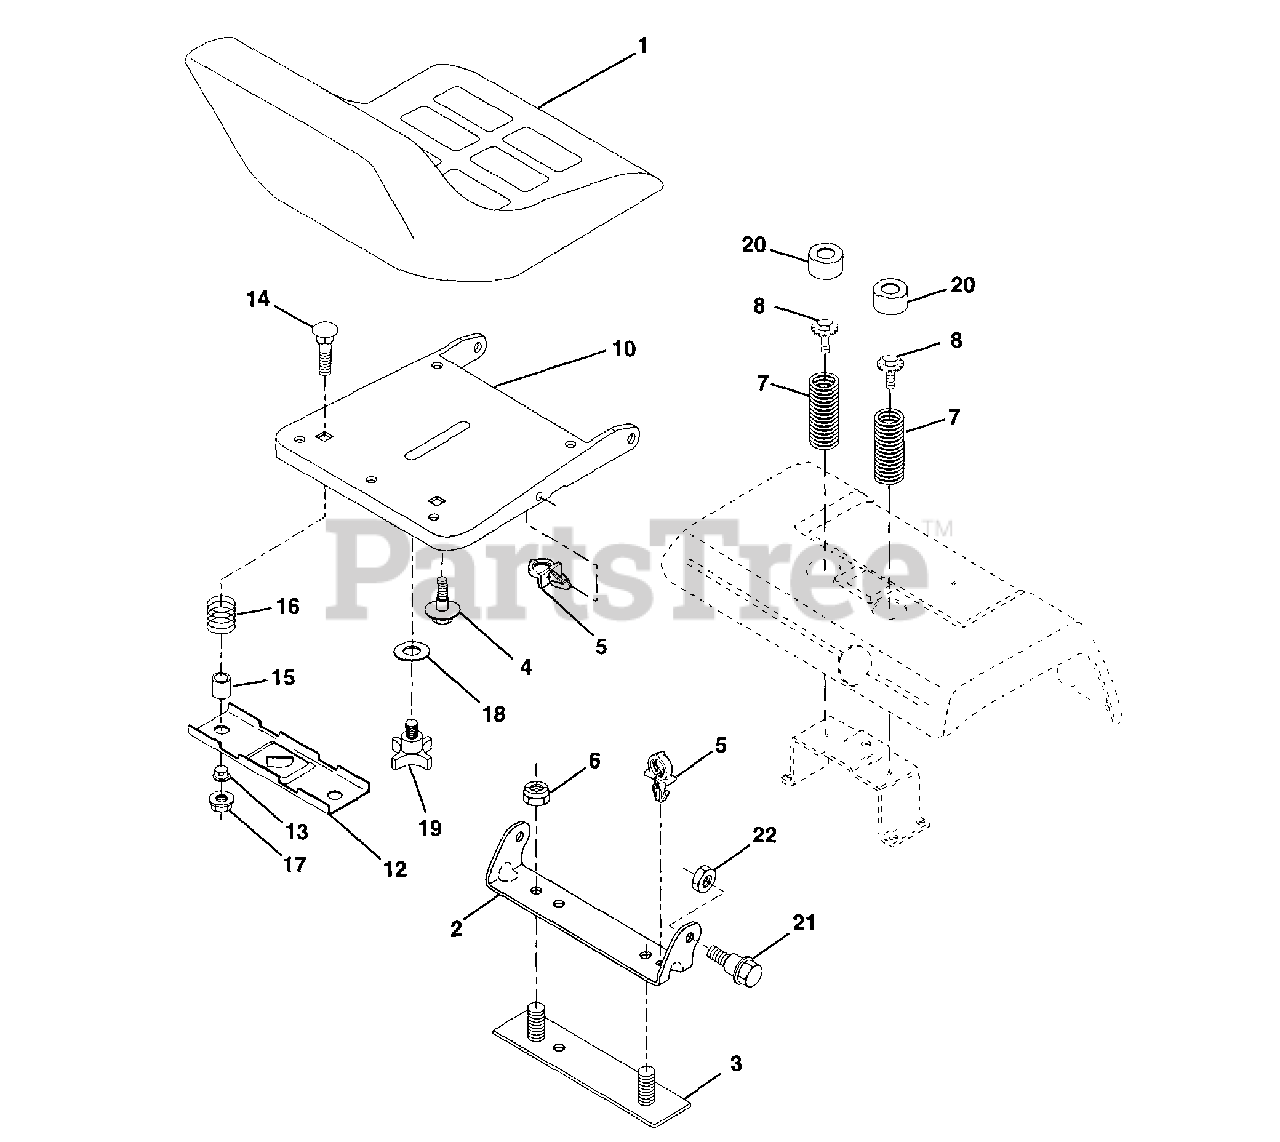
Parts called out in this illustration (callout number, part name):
1	Seat
2	Bracket, Pivot Seat
3	Strap, Fender
4	Bolt, Shoulder 5/16-18 X .62
5	Clip, Push In Hinged
6	Nut, Lock Hex W/Ins. 3/8-16 Unc
7	Spring, Seat Cprsn
8	Screw, Thdrol 5/16-18 X 1/2
9	Washer 13/32 X 1 X 14 Ga.
10	Pan, Seat
12	Bracket, Mounting Switch
13	Bushing, Snap
14	Bolt, Carriage 1/4-20 X 1-3/8
15	Spacer, Split
16	Spring, Cprsn
17	Nut, Lock 1/4 Lge Flg Gr. 5
18	Washer 17/32 X 1-3/16 X 12 Ga.
19	Knob, Seat 1/2-13 Unc
20	Cap, Spring Seat
21	Bolt, Shoulder 5/16-18 Unc
22	Nut, Crownlock 5/16-18 Unc
